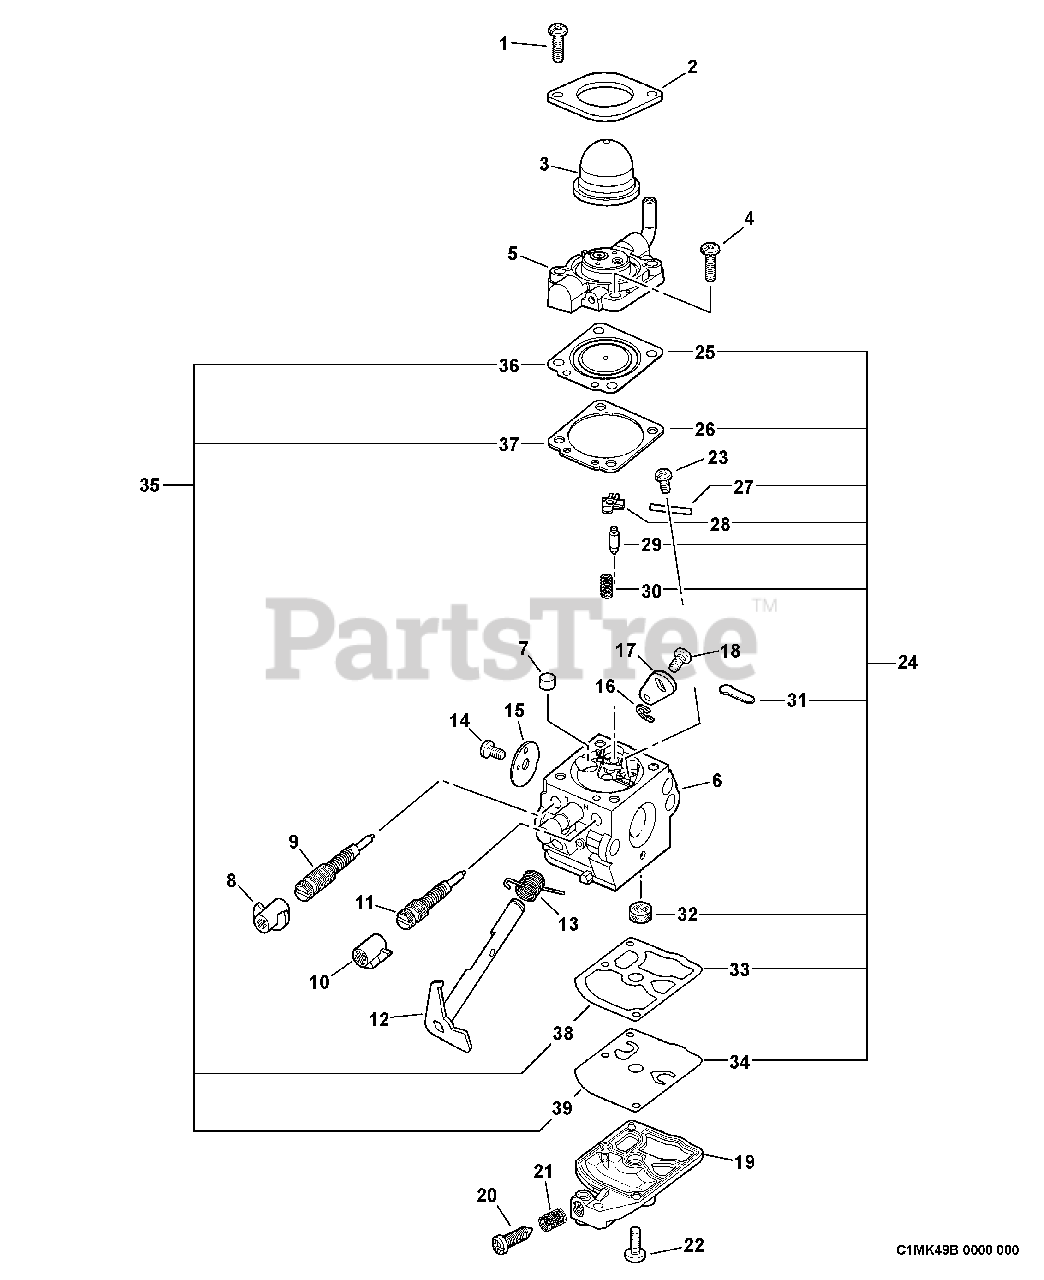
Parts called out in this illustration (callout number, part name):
1	SCREW, RETAINER
2	RETAINER, PURGE BULB
3	BULB, PURGE
4	SCREW, PURGE BASE
5	BASE, PURGE
6	BODY, CARBURETOR
7	NOZZLE, CHECK VALVE
8	CAP, LIMITER
9	NEEDLE - LOW SPEED
10	CAP, LIMITER
11	NEEDLE - HIGH SPEED
12	SHAFT, THROTTLE
13	SPRING, TRIGGER
15	VALVE, THROTTLE
16	RING, RETAINING
17	LEVER, THROTTLE
19	COVER, FUEL PUMP
20	SCREW, IDLE ADJUST
21	SPRING, IDLE ADJUST
22	SCREW, PUMP COVER
23	SCREW, METERING LEVER PIN
24	REPAIR KIT
25	DIAPHRAGM, METERING
26	GASKET, DIAPHRAGM
27	PIN, METERING LEVER
28	LEVER, METERING
29	VALVE, INLET NEEDLE
30	SPRING, METERING LEVER
31	PLUG, WELCH
32	STRAINER
33	GASKET, PUMP
34	DIAPHRAGM, PUMP
35	DIAPHRAGM/GASKET KIT
36	DIAPHRAGM, METERING
37	GASKET, DIAPHRAGM
38	GASKET, PUMP
39	DIAPHRAGM, PUMP
